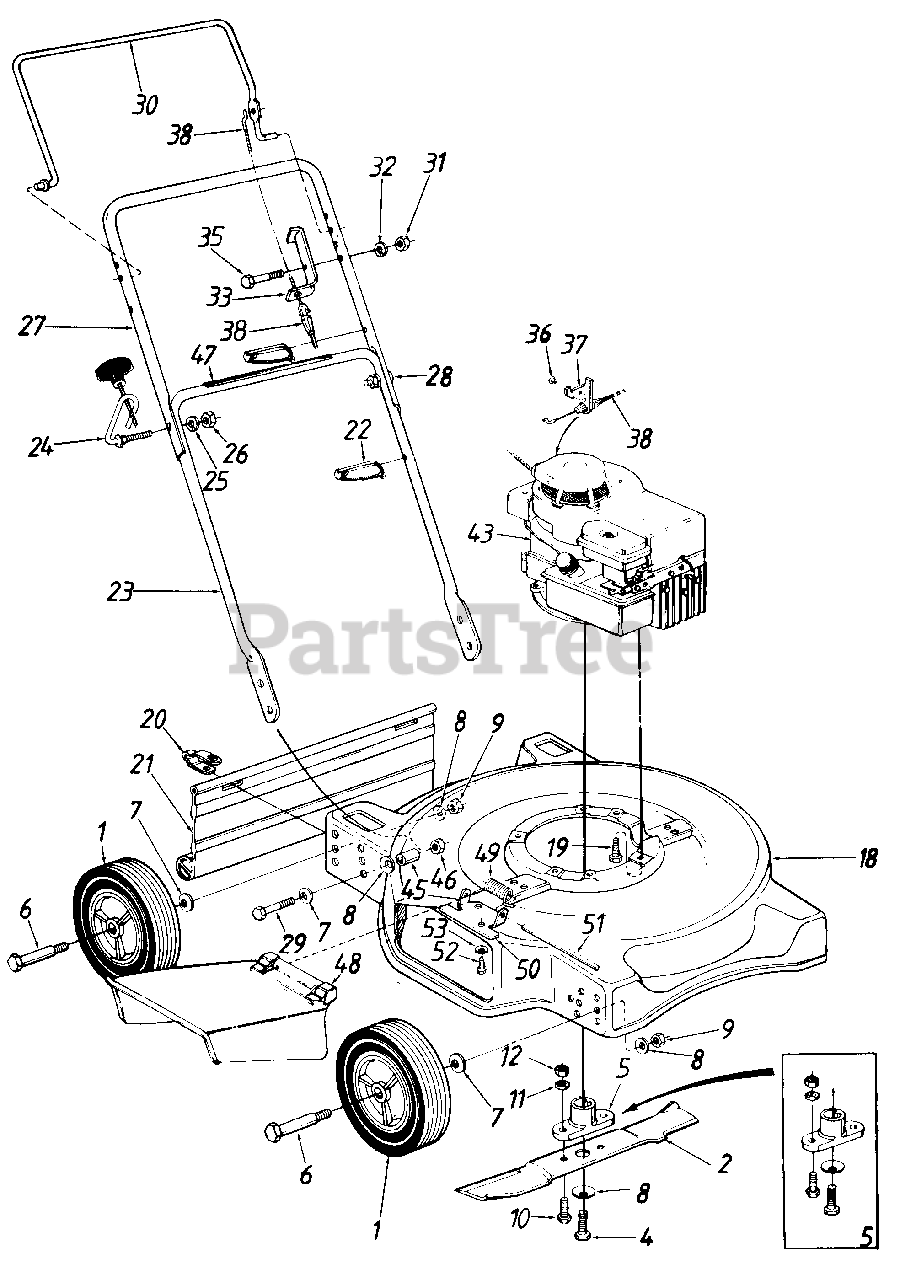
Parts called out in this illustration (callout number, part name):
1	Wheel Ass'y. Complete
2	20" Blade
4	Hex Bolt 3/8-24 x 1.5" Lg.
5	Blade Adapter Kit (Keyed)
6	Shld. Bolt .498" Dia. x 1.64"
7	Bell-Wash. .380" I.D. x .88"
8	Bell-Wash. .39" I.D. x 1.13
9	Hex Nut 3/8-16 Thd.*
10	Hex Bolt 3/8-24 x 1 " Lg.
11	L-Wash. 3/8" I.D.*
12	Hex Nut 3/8-24 Thd.
18	20" Deck Ass'y.
19	Hex Wash. Hd. Scr. 3/8-16 x 1" Lg.
20	Hinge Clip
21	Rear Flap 16.75" Lg.
22	Cable Tie
23	Lower Handle
24	Rope Guide Bolt
25	L-Wash. 5/16" I.D.
26	Hex Nut 5/16-18 Thd.
27	Upper Handle
28	Curved Carriage Bolt 5/16-18 x 1.38" Lg.
29	Hex Bolt 3/8-24 x 1.5" Lg.
30	Control Handle
31	Hex Nut 1/4-20 Thd.*
32	Spr. Wash. .265" l.D. x .562"
33	Cable Mounting Bracket
35	Hex Bolt 1/4-20 x 1.25" Lg.*
37	Cable Bracket
38	Control Cable-36"
45	Spacer .381" I.D. x .56" O.D. x .75" Lg.
46	Hex L-Nut 3/8-24 Thd.
47	Instruction Label-Handle
48	Chute Deflector Ass'y.
49	Torsion Spring
50	Adapter Plate
51	Hinge Pin
52	Hex Self-Tap Scr. 1/4-20 x .5" Lg.
53	Bell-Wash. 1/4" I.D.
